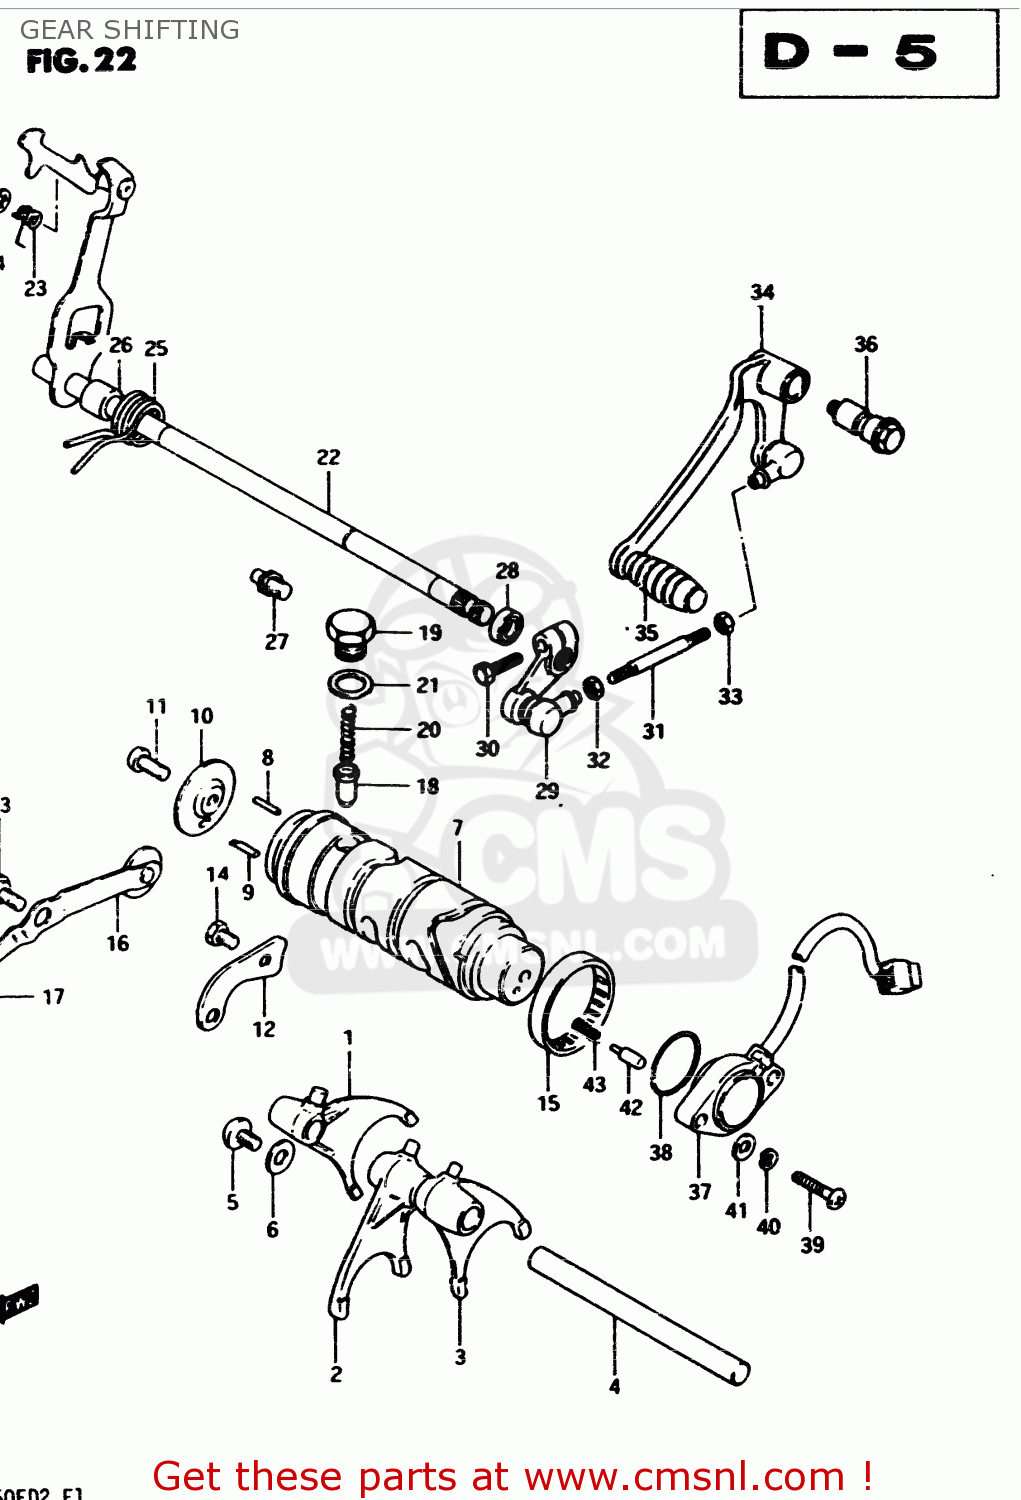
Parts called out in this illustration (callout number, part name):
1	FORK,GEAR SHIFT NO.1
2	FORK,GEAR SHIFT NO.2
3	FORK,GEAR SHIFT NO.2
4	SHAFT,GEAR SHIFT FORK
5	SCREW
6	WASHER
7	CAM,GEAR SHIFT
8	PIN(4X18.5)
9	PIN
10	RETAINER,GEAR SHIFT CAM DR PIN
11	SCREW
12	GUIDE,GEAR SHIFTING CABLE
13	BOLT
14	BOLT, UPPER
15	BEARING(40X47X12)
16	STOPPER,GEAR SHIFT CAM NO.1
17	SPRING
18	STOPPER,GEAR SHIFT CAM NO.2
19	HOLDER,GEAR SHIFT CAM STOP SPR
20	SPRING
21	GASKET(14X19.2X2) (NAS)
22	SHAFT,GEAR SHIFT
23	SPRING
24	E RING
25	SPRING
26	SPACER(12X20X15.3)
27	STOPPER,GEAR SHIFT CAM
28	OIL SEAL
29	ARM,GEAR SHIFT LINK
30	BOLT
31	ROD,GEAR SHIFT LINK
32	NUT
33	NUT
34	LEVER ASSEMBLY,GEAR SHIFTING
35	RUBBER,GEAR SHIFT PEDAL
36	SHAFT,GEAR SHIFT LEVER
37	BASE ASSEMBLY,NEUTRAL SWITCH TERMINAL
38	O-RING (D:2.4 ID:26.2)
39	SCREW 5X20
40	LOCK WASHER
41	WASHER
42	PIN(5X15.5)
43	SPRING
